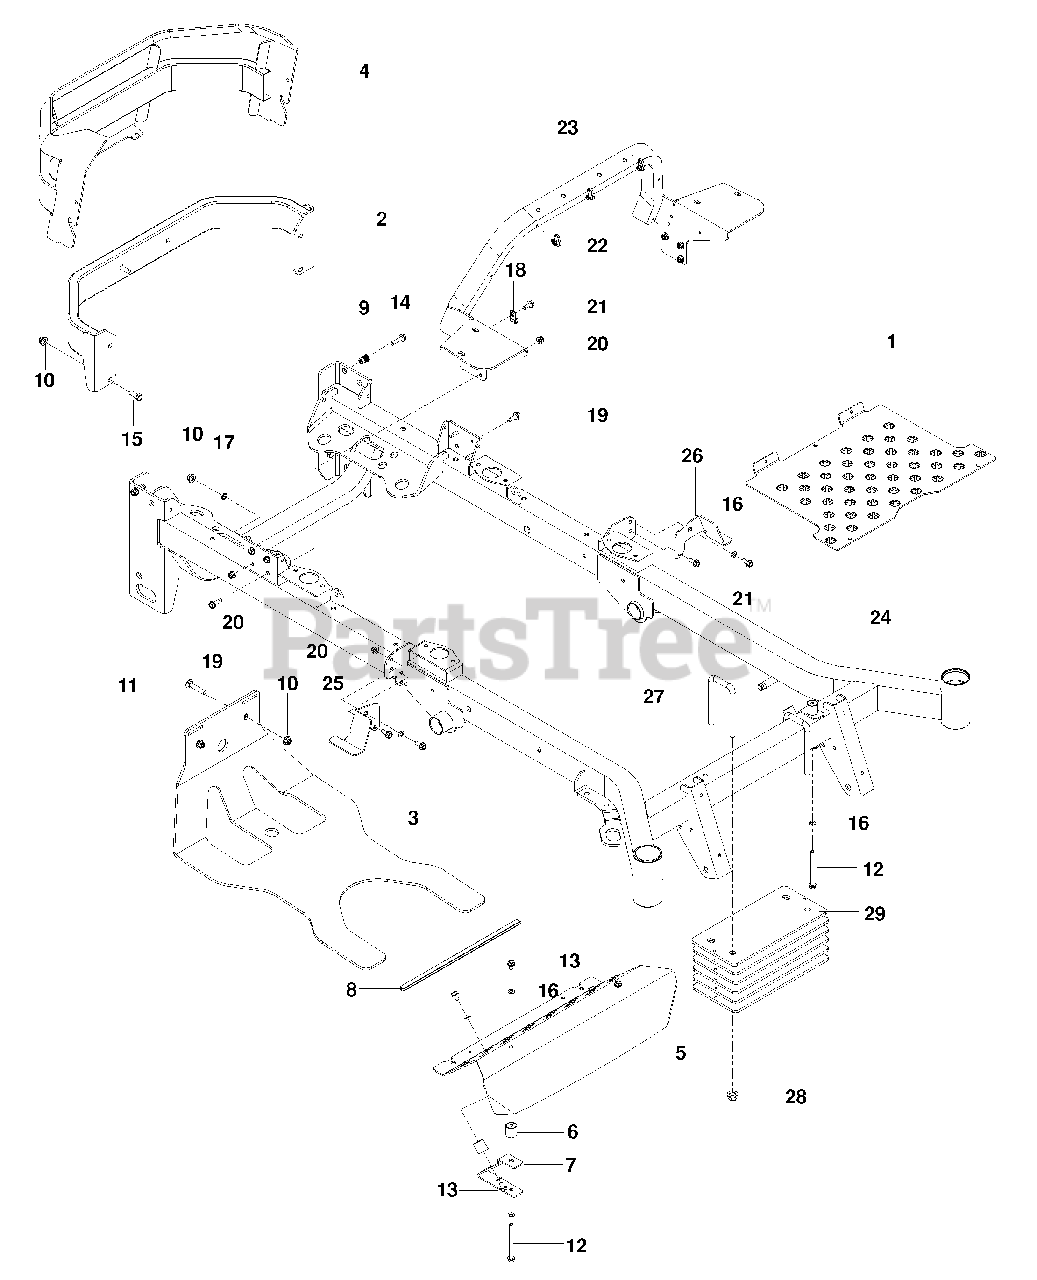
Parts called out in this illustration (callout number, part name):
1	Floorpan Org
2	Bumper, Rear Org W/ Decal
3	Plate, Skid Gry
4	Guard, Rear Gry W/ Decals
5	Foot Rest Org
6	Mount, F/F Insert
7	Bracket, Rest Mount
8	Flex Trim Blk
9	Nutsert 5/16-18
10	Nut 3/8-16 Hex Flg Nyloc
11	Bolt 3/8-16 X 2 Rd Hd
12	Screw 5/16-18 X 3 3/4 Hex Flg
13	Screw 5/16-18 X 1/2 Slf Tap
14	Screw 5/16-18 X 1 1/4 Tpblt
15	Screw 3/8-16 X 1 Hex Hd
16	Washer 5/16 Disc Spring
17	Washer 3/8 Ext Star
18	Clamp, Double Tube
19	Bolt 5/16-18 X 1 Thd Frm
20	Nut 5/16-18 Hex Flange Nyloc
21	Hhfs 5/16-18 X 3/4
22	Tie Wrap W/ Clip
23	Cross Member, Gry
24	Frame Org
25	Mount, Tank Rt Org
26	Mount, Tank Lt Org
27	Linkage, U-Bolt
28	Nut 1/2-13 Hex Flg Nyloc
29	Plate, Weigh Blk
